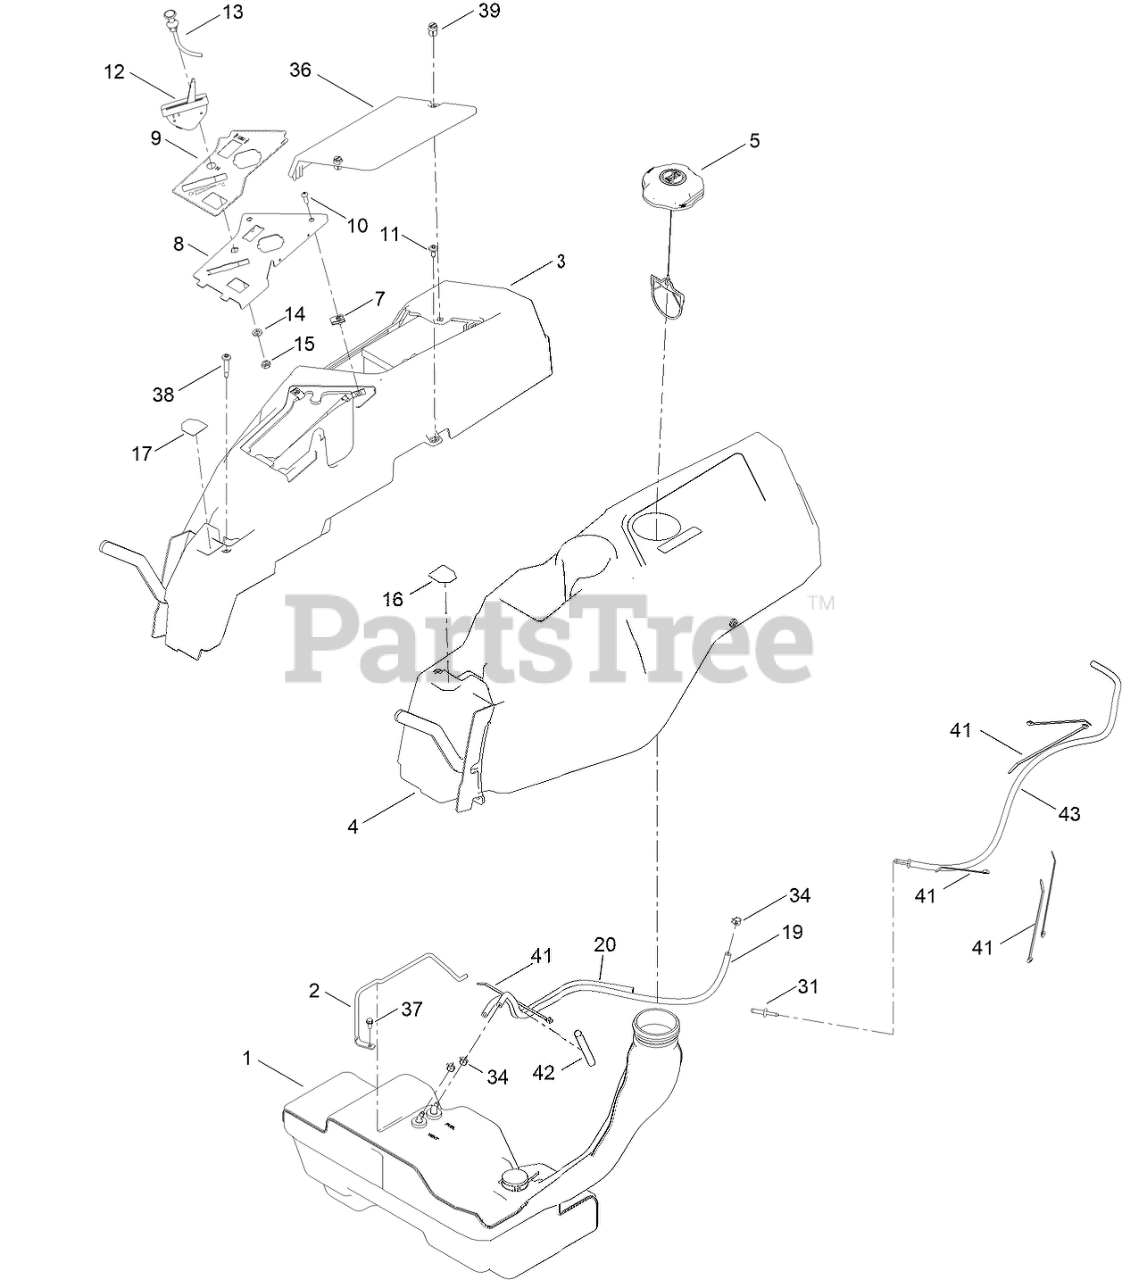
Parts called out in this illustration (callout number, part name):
1	TANK-FUEL ASM
2	ROD-HOLD DOWN
3	POD-RH
4	POD-LH
5	CAP-FUEL, RATCHETING
8	PANEL-CONTROL
9	DECAL-PANEL, CONTROL
10	SCREW-PRH
11	SCREW-SHOULDER
12	CABLE-THROTTLE
13	CABLE-CHOKE
14	WASHER-LOCK
15	NUT-HJ
16	DECAL-LEVER, CONTROL (LH)
17	DECAL-LEVER, CONTROL (RH)
19	HOSE-FUEL
20	HOSE-VENT
31	ADAPTER ORIFICE
34	CLAMP-HOSE
36	COVER-BATTERY
37	SCREW-HWH
38	SCREW-SHOULDER
39	FASTENER
41	TIE-CABLE
42	SLEEVE-FUEL LINE PROTECTOR
